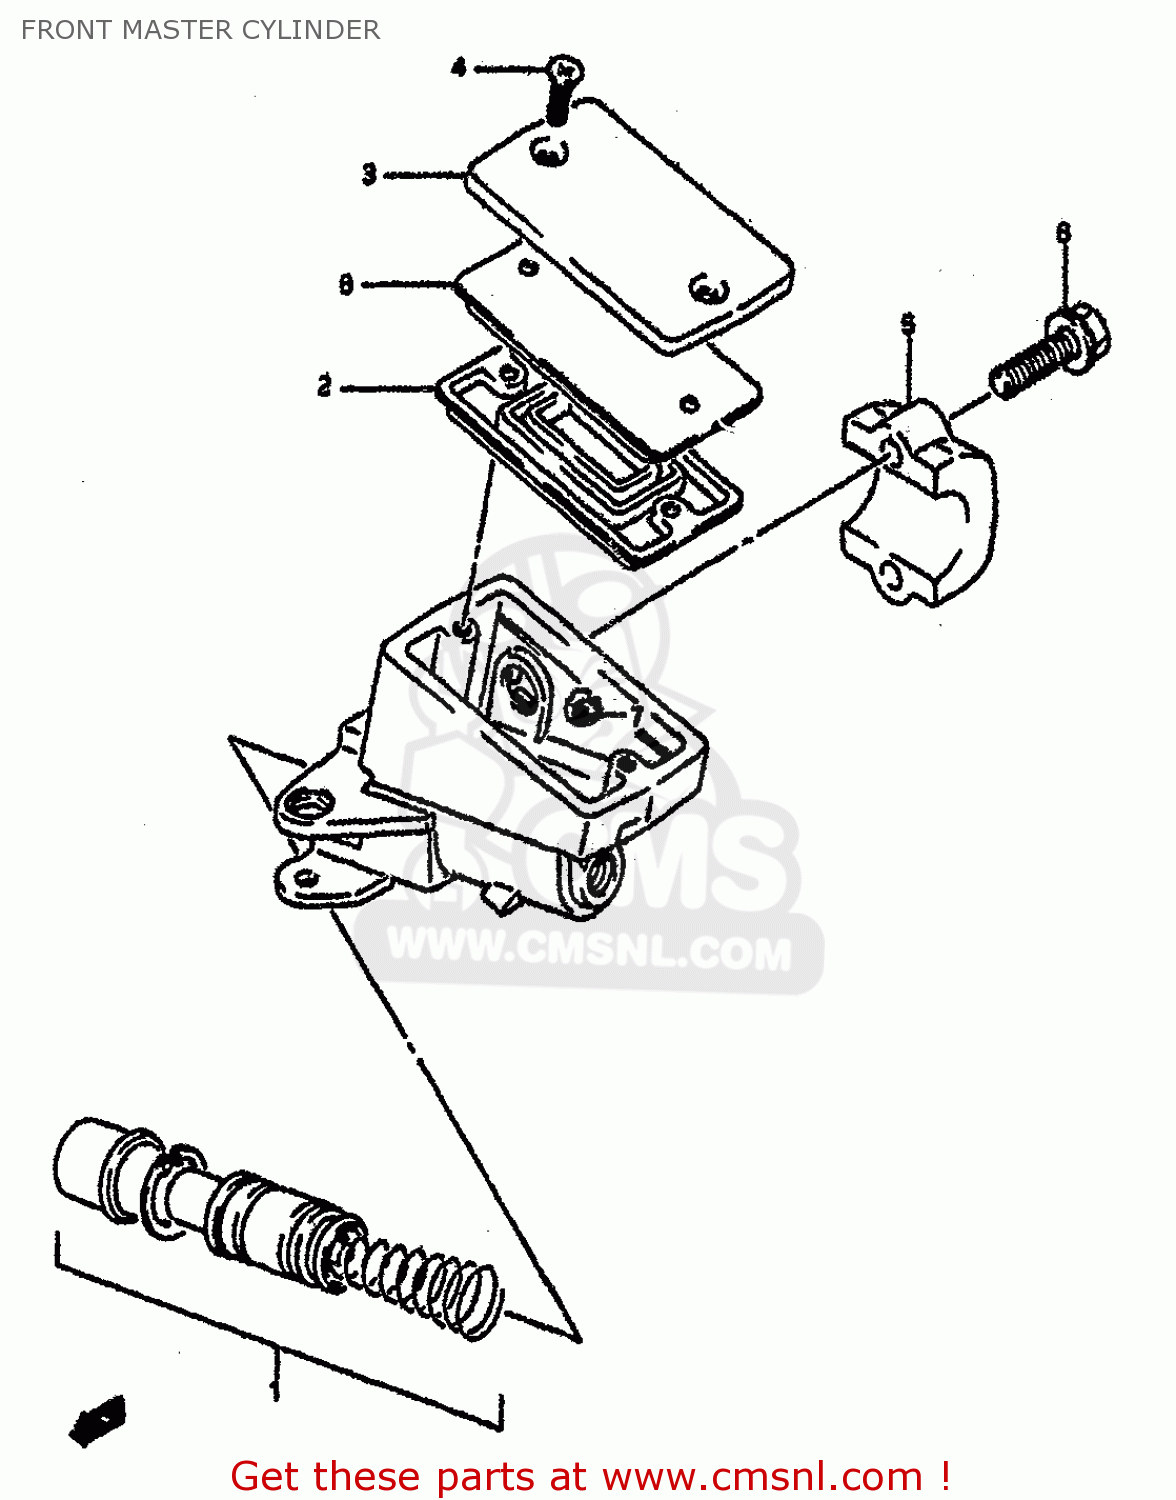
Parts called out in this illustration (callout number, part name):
1	PISTON & CUP SET
2	3
3	CAP
4	SCREW
5	HOLDER
6	BOLT
7	PROTECTOR
8	PLATE,DIAPHRAGM
